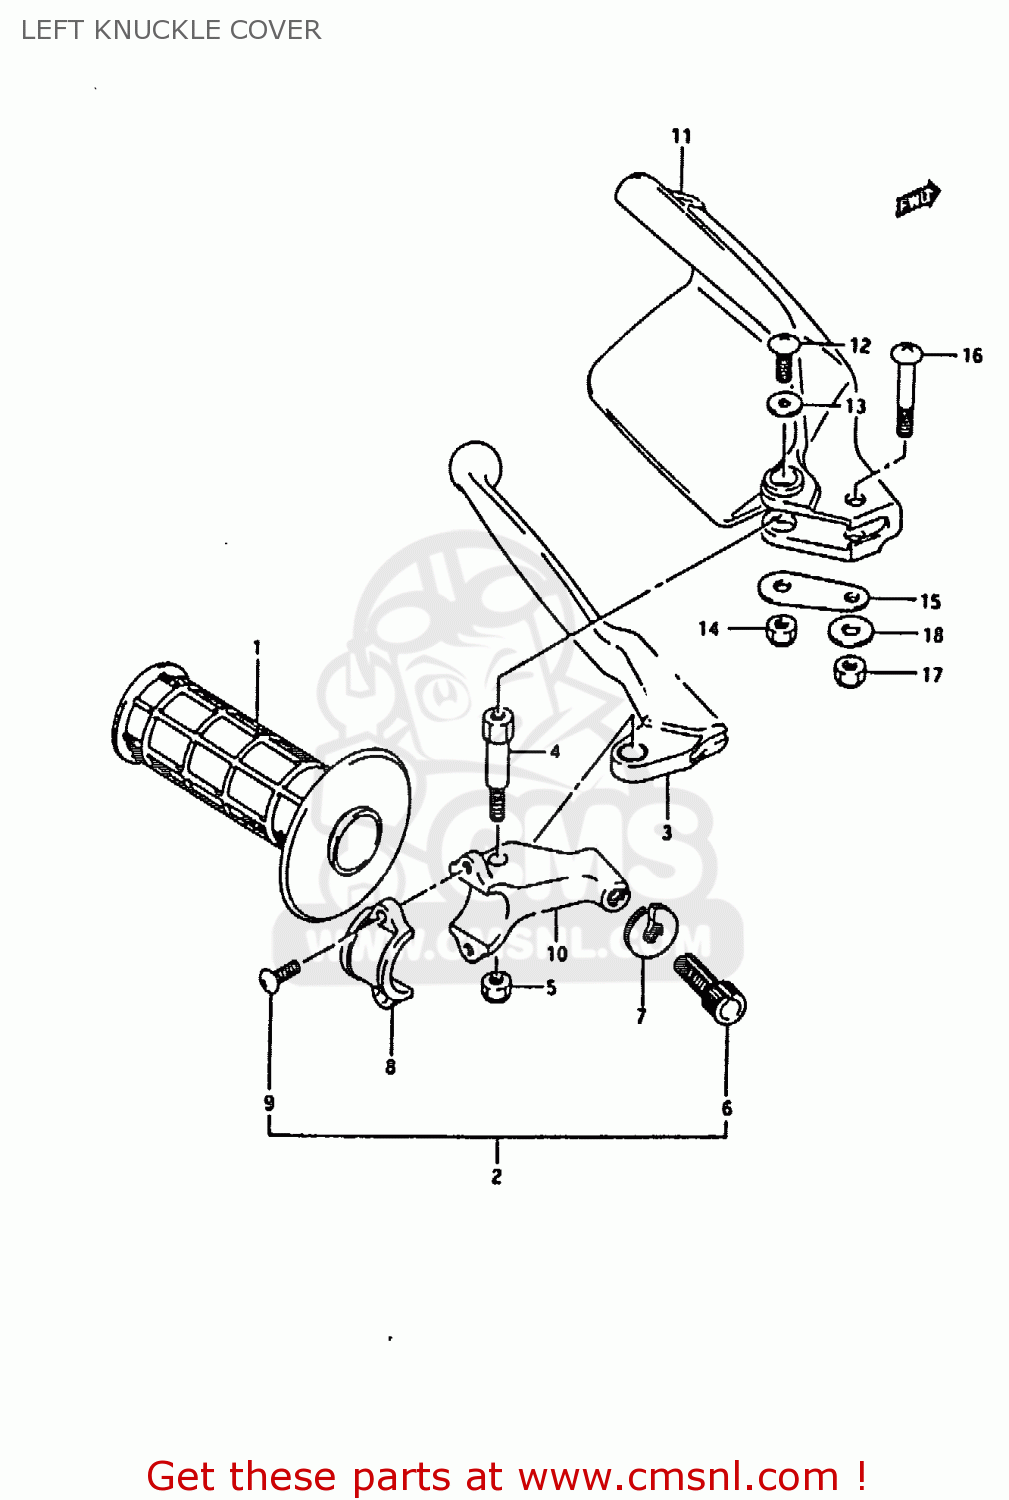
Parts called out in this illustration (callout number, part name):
1	GRIP,L
2	LEVER ASSY,CLUTCH
3	LEVER,CLUTCH
4	BOLT,LEVER SET
5	NUT 6MM
6	ADJUSTER,CABLE
7	NUT,LOCK
8	BRACKET,CLUTCH LEVER HOLDER
9	SCREW(5X14)
10	HOLDER,CLUTCH LEVER
11	COVER,KNUCKLE,L
12	SCREW
13	WASHER (5.5X16X1.2)
14	NUT 6MM
15	PLATE,KNUCKLE COVER,L LWR
16	SCREW(6X35)
17	NUT
18	WASHER (6.5X17X1.6)
